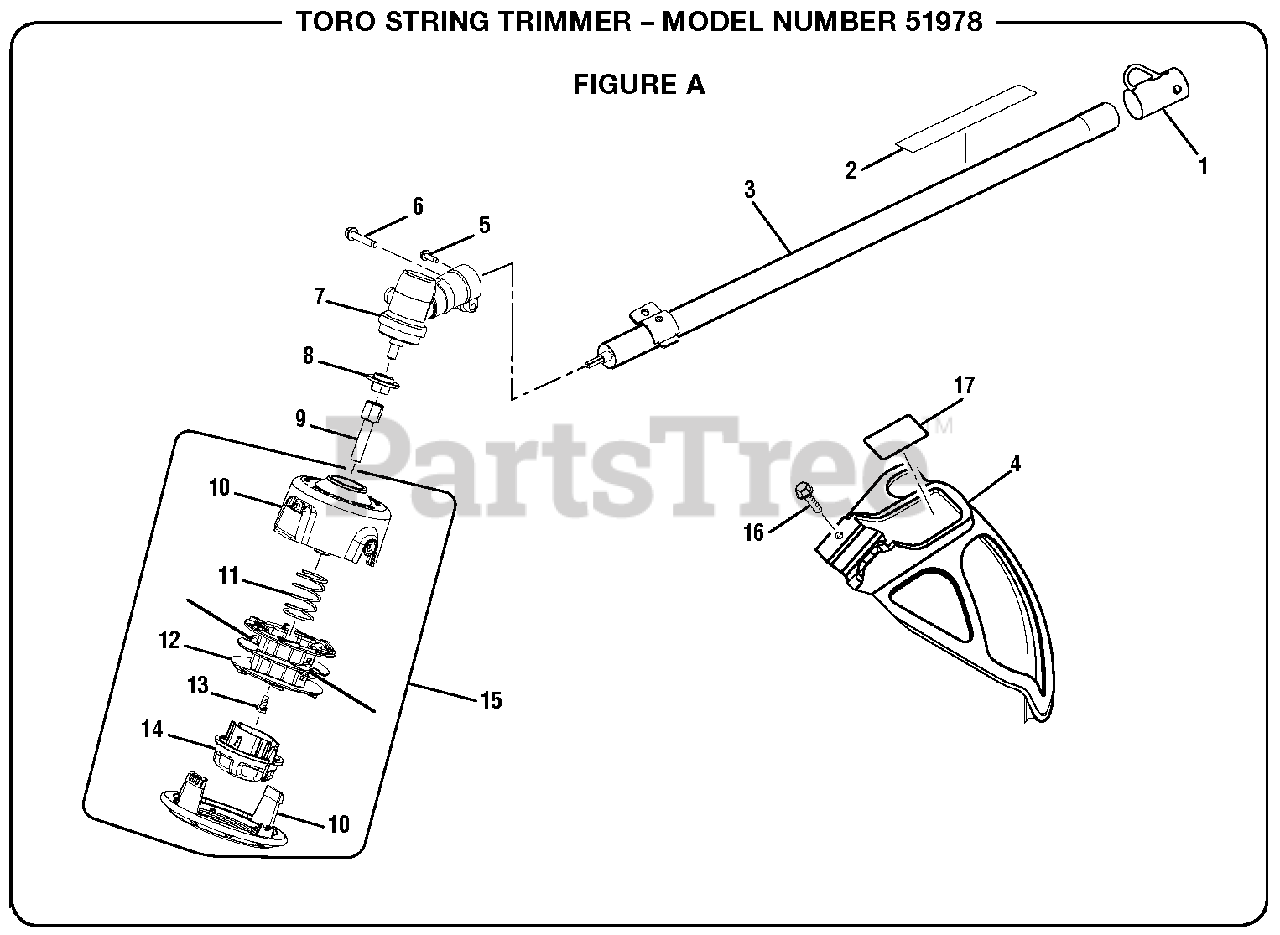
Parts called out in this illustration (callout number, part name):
1	Hanger Cap
2	Warning Label
3	Straight Shaft Assembly
4	Grass Deflector Assembly
5	Screw (10-24 x 5/8 in., Hex Washer Hd.)
6	Screw (1/4-20 x 1-1/4 in.)
7	Gear Head Assembly
8	Flanged Washer
9	Trimmer Head Shaft Adaptor
10	Stringhead Housing
11	Compression Spring
12	Spool
13	Bolt (5/16-18 x 1/2 in., L.H.)
14	Bump Knob
15	Trimmer Head Assembly (.095)
16	Screw (1/4-20 x 1-1/4 in., Hex Washer Hd.)
17	Grass Deflector Label
